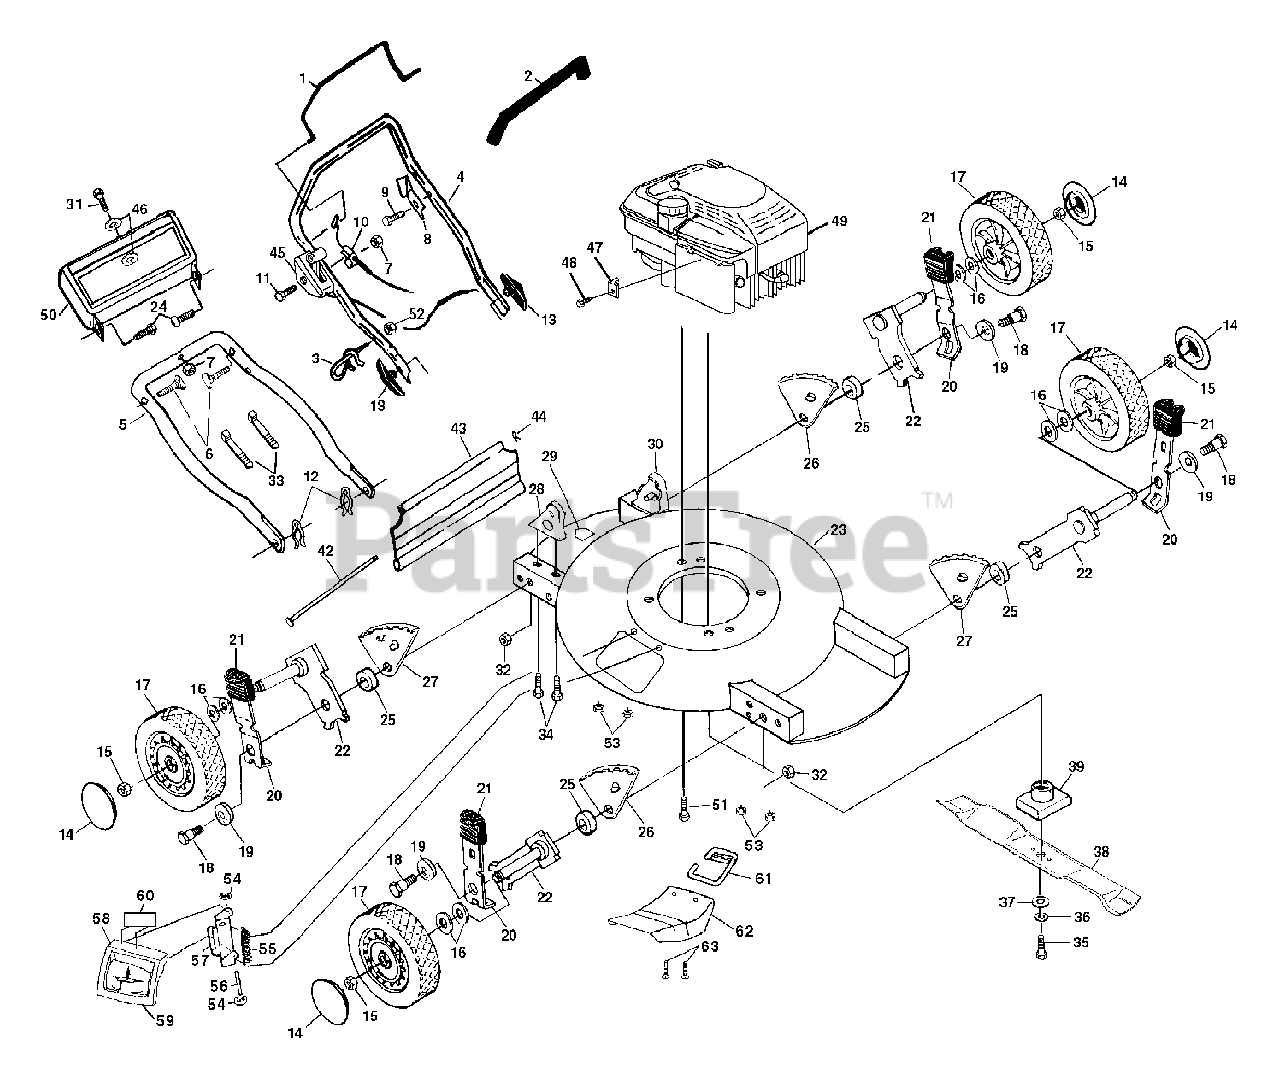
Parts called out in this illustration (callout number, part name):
1	Control Bar
2	Handle Grip
3	Rope Guide
4	Upper Handle
5	Lower Handle
6	Handle Bolt 5/16-18 x 1-3/4
7	Locknut 1/4-20
8	Up-Stop Bracket
9	Hex Washer Head Screw #10-24 x 1/2
10	Engine Zone Control Cable
11	Hex Washer Head Screw 1/4-20 x 2.12
12	Hairpin Cotter
13	Handle Knob
15	Hex Locknut 3/8-16
16	Washer
17	Wheel & Tire Assembly
18	Shoulder Bolt
19	Belleville Washer
20	Selector Spring
21	Selector Knob
22	Axle Arm Assembly
23	Lawn Mower Housing
25	Spacer
26	Wheel Adjusting Bracket (R.F./L.R.)
27	Wheel Adjusting Bracket (L.F./R.R.)
28	Handle Bracket Assembly (Right)
29	Danger Decal
30	Handle Bracket Assembly (Left)
31	Screw
32	Locknut 3/8-16
33	Wire Tie
34	Thread Cutting Screw 5/16-18 x 3/4
35	Hex Head Screw 3/8-24 x 1-3/8
36	Helical Lockwasher 3/8
37	Hardened Washer
38	20" Blade
39	Blade Adapter
42	Deflector Rod
43	Rear Deflector
44	Retainer Clip
45	Throttle Control
47	Cable Clamp
48	Thread Rolling Screw #10-32 x 5/8
50	Trim Plate
51	Hex Head Screw, Self Tap. 3/8 - 16 x 1.1
52	Keps Locknut 1/4-20
53	Locknut
54	External E-Ring
55	Torsion Spring
57	Housing Assembly Bracket
58	Mulcher Door
59	Door Latch
61	Chute Mounting Bracket
62	Mulcher Deflector
63	Truss Head Screw
